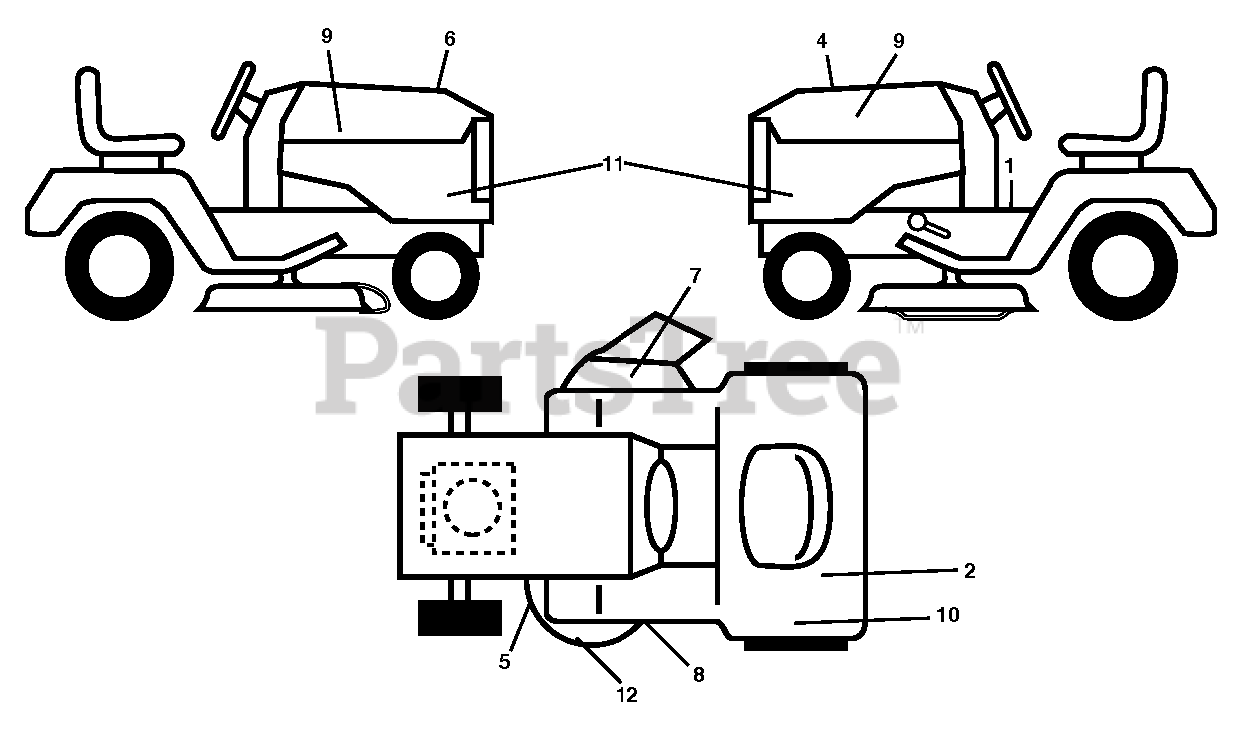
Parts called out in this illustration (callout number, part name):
1	DECAL.WARNING.2007.ENG/FR
5	DECAL.MOWER.CAUTION.TENSION.AR
6	DECAL.E85.WARNING.2012
7	DECAL, DECK DEFLECTOR, WARNING
8	DECAL.MOWER.SCH.48/54.PREM
9	DECAL.BADGE.170MM.TEXTLOGO.
10	DECAL.DECK.BUILTINAMERICA.HUSQ
11	DECAL.SDPNL.SET.YTH24K54
12	DECAL.DECK.STAMP.BIOCLIPCMP.HU
